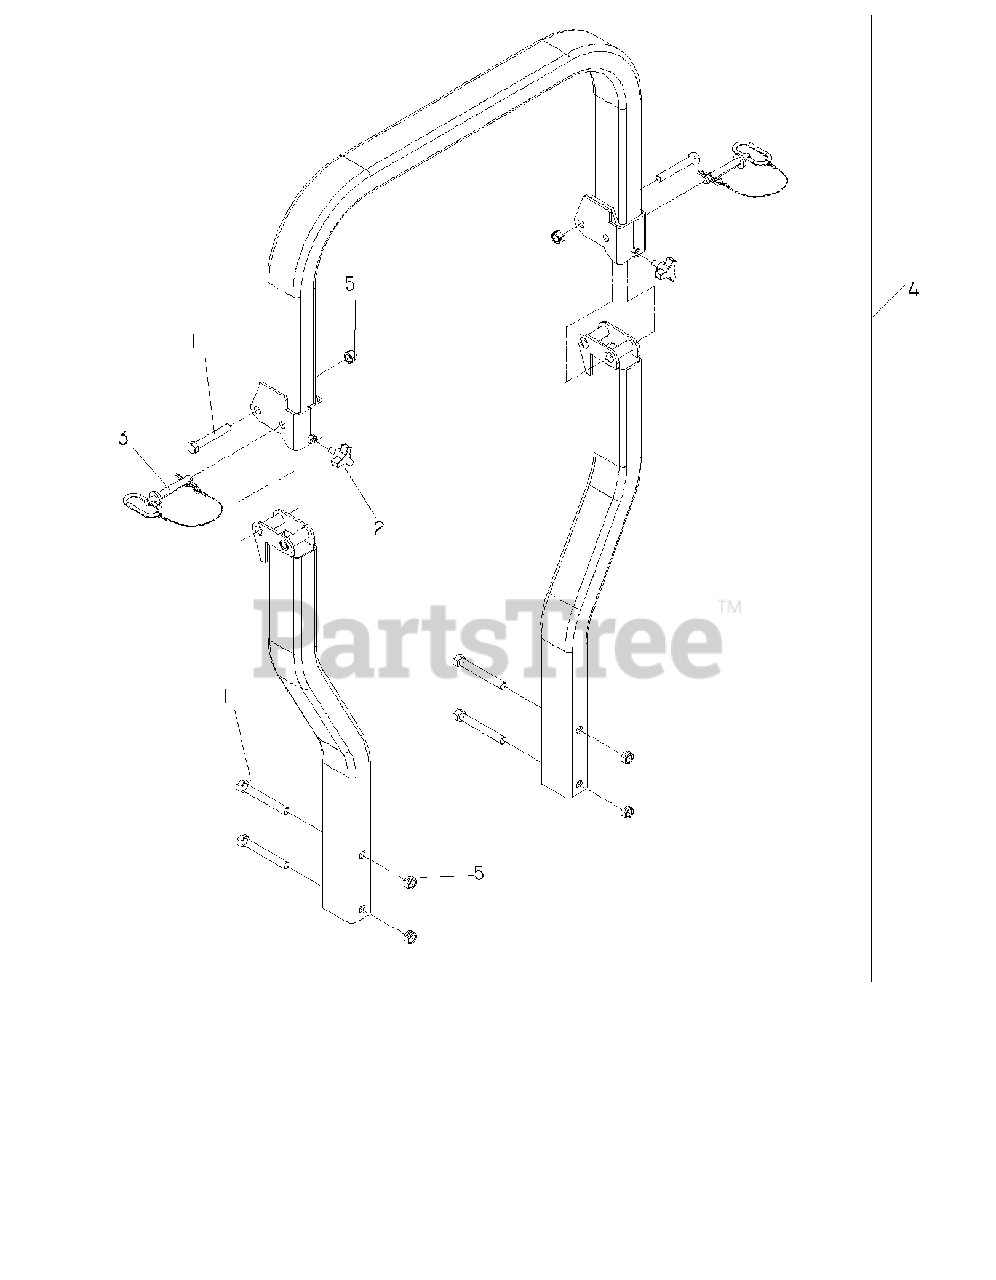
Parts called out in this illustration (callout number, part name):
1	HCS 1/2C X 3 1/4
2	KNOB W/STUD
3	PIN, 1/2" W/LANYARD
4	ROLL OVER PROTECTION SYSTEM
5	NUT 1/2-13 HEX CNTRLK GR 5 ZD
